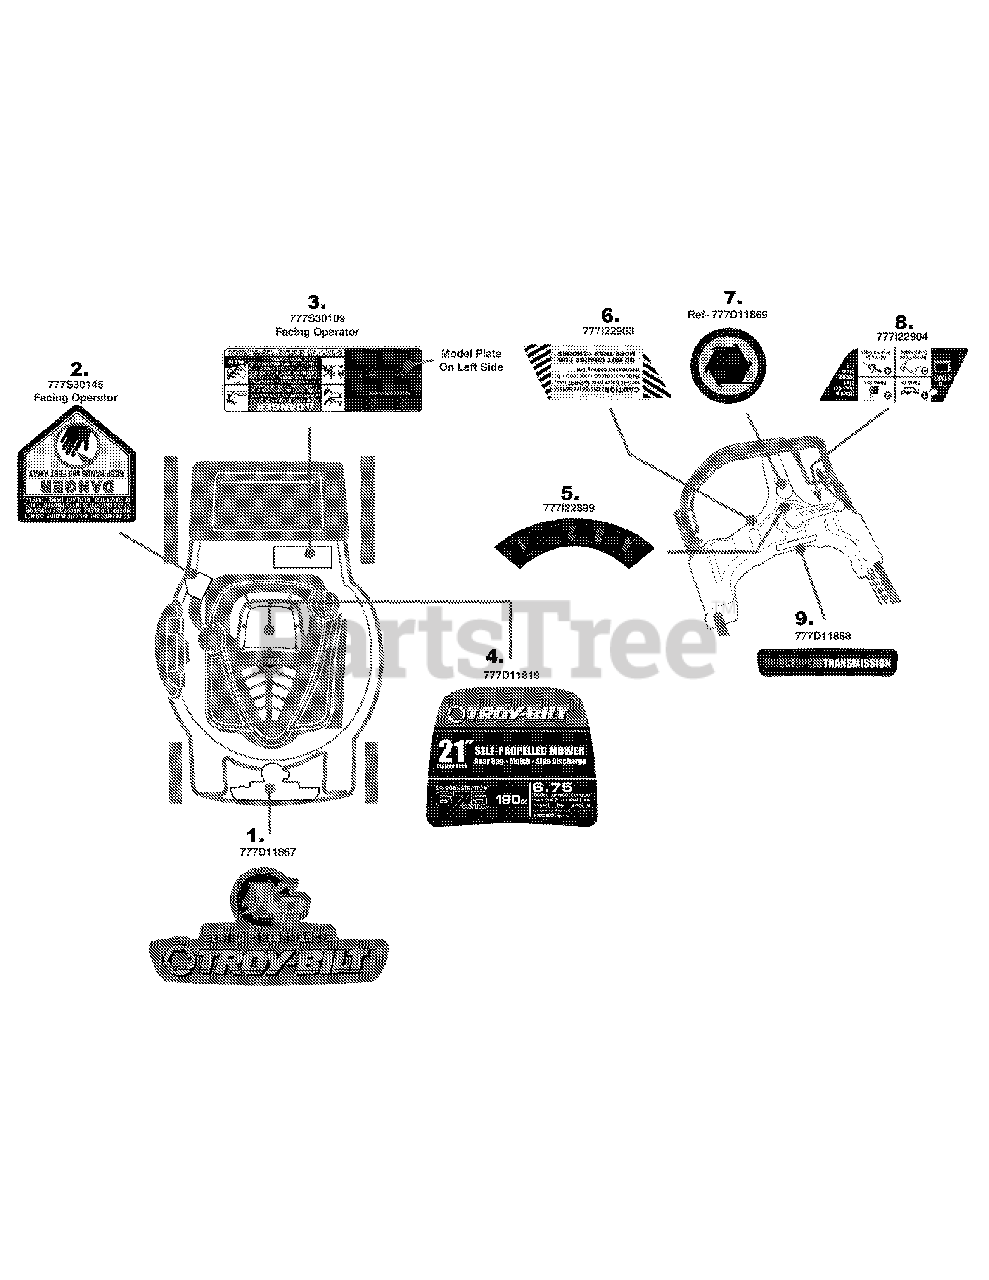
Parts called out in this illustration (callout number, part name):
1	LABEL-MOWER 800 XP TROY
2	LABEL
3	LABEL-MOWER DANGER
4	LABEL-MOWER SHROUD
5	LABEL-MOWER XP HANDLE SELECT
6	LABEL-MOWER HANDLE
7	LABEL-EMBOSSED TROYBILT
8	LABEL-MOWER HANDLE B & S
9	LABEL-MOWER XP HANDLE SELECT TROY
